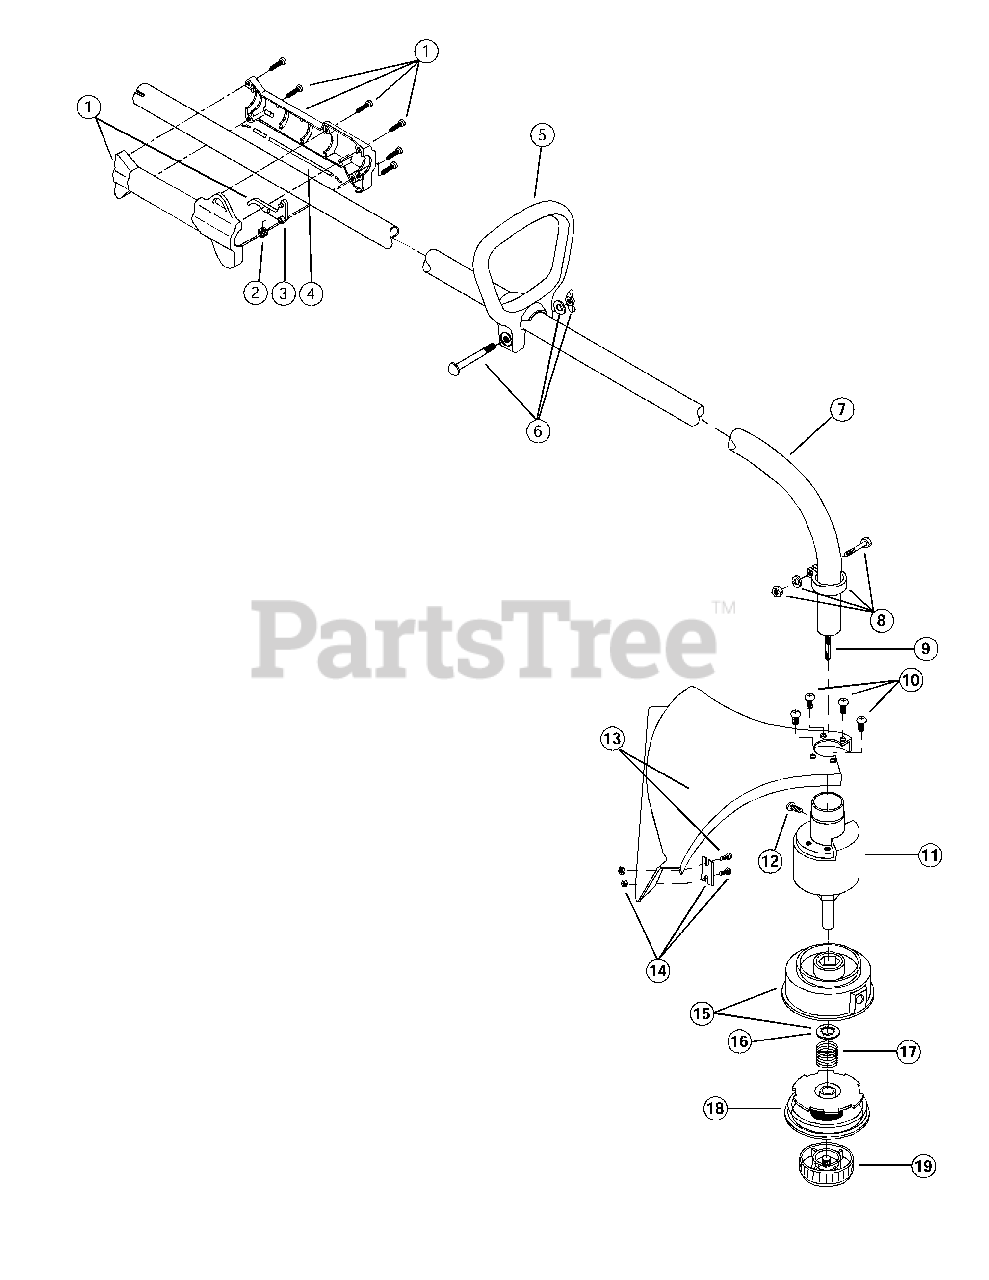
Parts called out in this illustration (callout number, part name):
1	Throttle Housing and Trigger Assembly
2	Throttle Trigger Spring
3	Throttle Trigger
4	Throttle Cable Assembly
5	D-Handle Assembly
6	D-Handle Hardware
7	Drive Housing
8	Lower Clamp Assembly
9	Flexshaft
10	Shield Mounting Screw Assembly
11	Bushing Housing Assembly with Spool Shaft
12	Anti-Rotation Screw
13	Shield & Blade Assembly
14	Blade Assembly
15	Outer Spool & Eyelet
16	Retainer
18	Inner Reel
19	Bump Head (TM) Assembly
